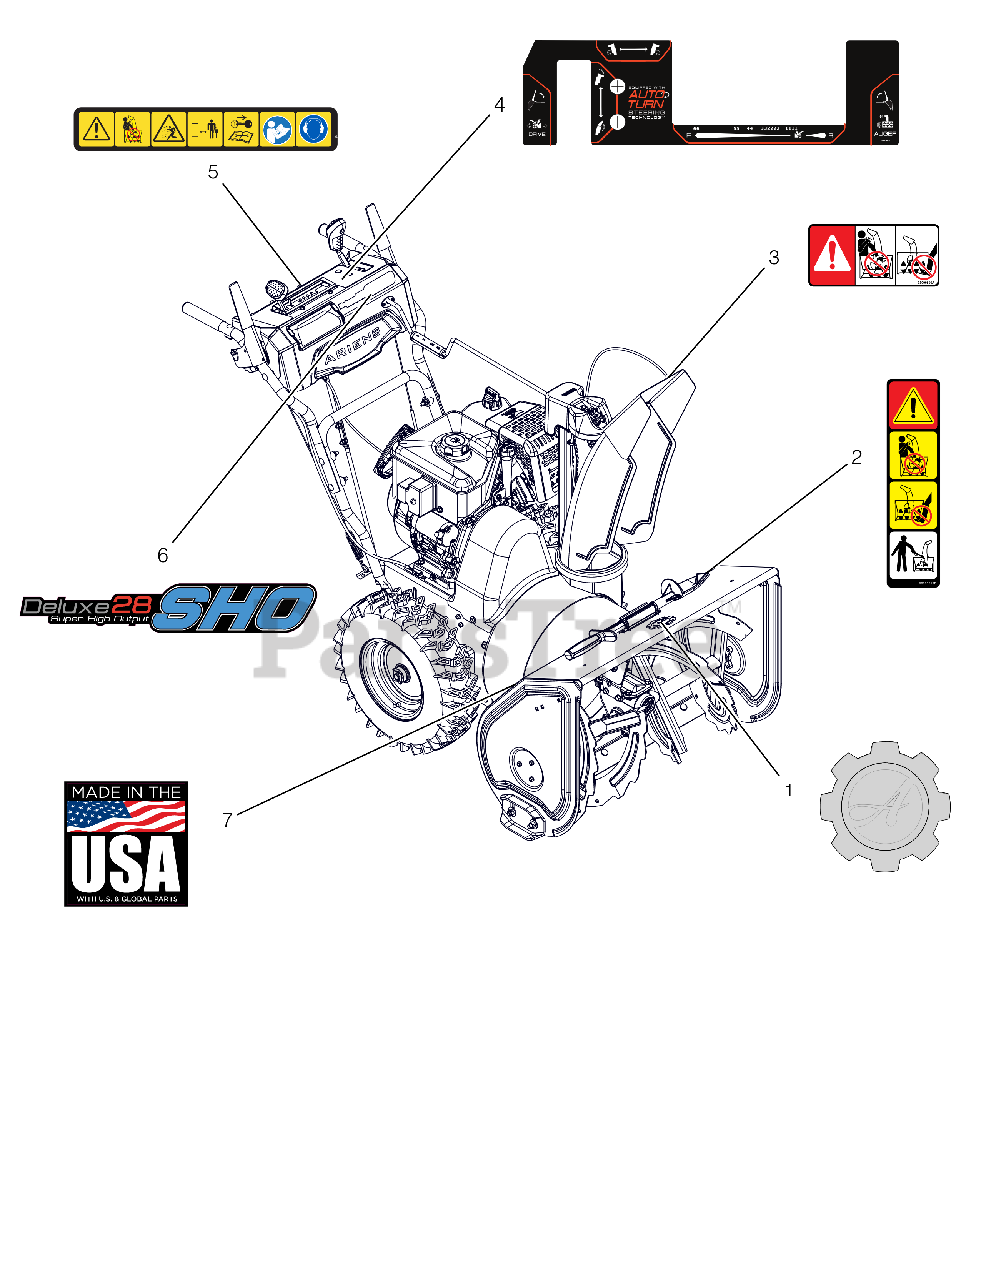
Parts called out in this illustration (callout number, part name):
1	DECAL, ARIENS-GEAR BADGE -THK
2	DECAL, DANGER - ROTATING PARTS
3	DECAL, DANGER
4	DECAL,CONTROL-SML,AT,ID
5	DECAL,DASH - SAFETY
6	DECAL,SMALL DASH-DLX 28 SHO
7	DECAL, MADE IN USA
